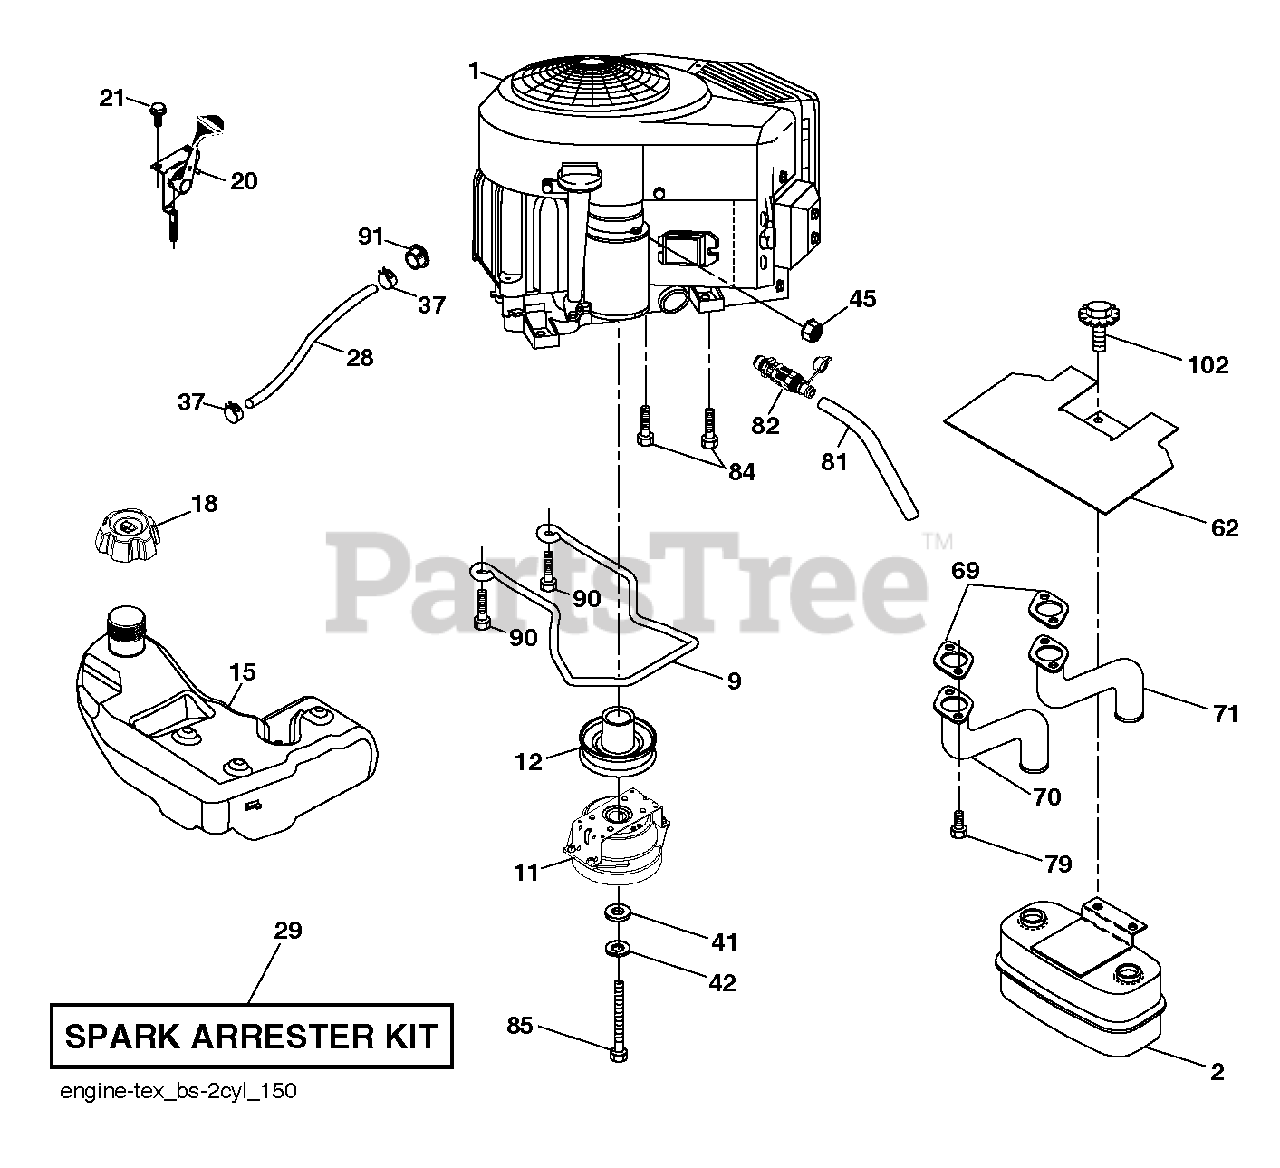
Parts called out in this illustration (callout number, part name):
2	MUFFLER.ASM.TWN.EXTNDED.DFLCTR
9	KEEPER.BELT.ENG.4.25"2.BLT.431
11	CLUTCH.OGURA.4.4PD.GT1.5-EH13V
12	PULLEY.ENGINE.TUFFTORQ
15	TANK.ASSY.3.GAL.EPA
18	CAP ASSY FUEL 3" GRAY
20	CONTROL.TH/CK.COBRA.B&S.TWN.
21	SCREW.#10 X 0.750.BOS
28	LINE.FUEL.64"REAR.EMIS
29	KIT.SPARK ARRESTOR 794945 B&S
37	HOSE CLAMP
42	LOCKWASHER
45	NUT
62	SHIELD.HEAT.MUFFLER
69	GASKET.MUFFLER
70	EXHAUST.TUBE.LH.BS/TWIN
71	EXHAUST.TUBE.RH.B&S.TWIN.INTEK
79	SCREW.SOCKET.HEAD.5/16-18
81	TUBE, DRAIN OIL ASM.
82	VALUE.OIL.DRAIN
84	SCREW.3/8-16
85	CLUTCH BOLT7/16-20X3.5 GR524HR
90	SCREW 3/8-16X1
91	BUSHING.1.375OD
102	SCREW
